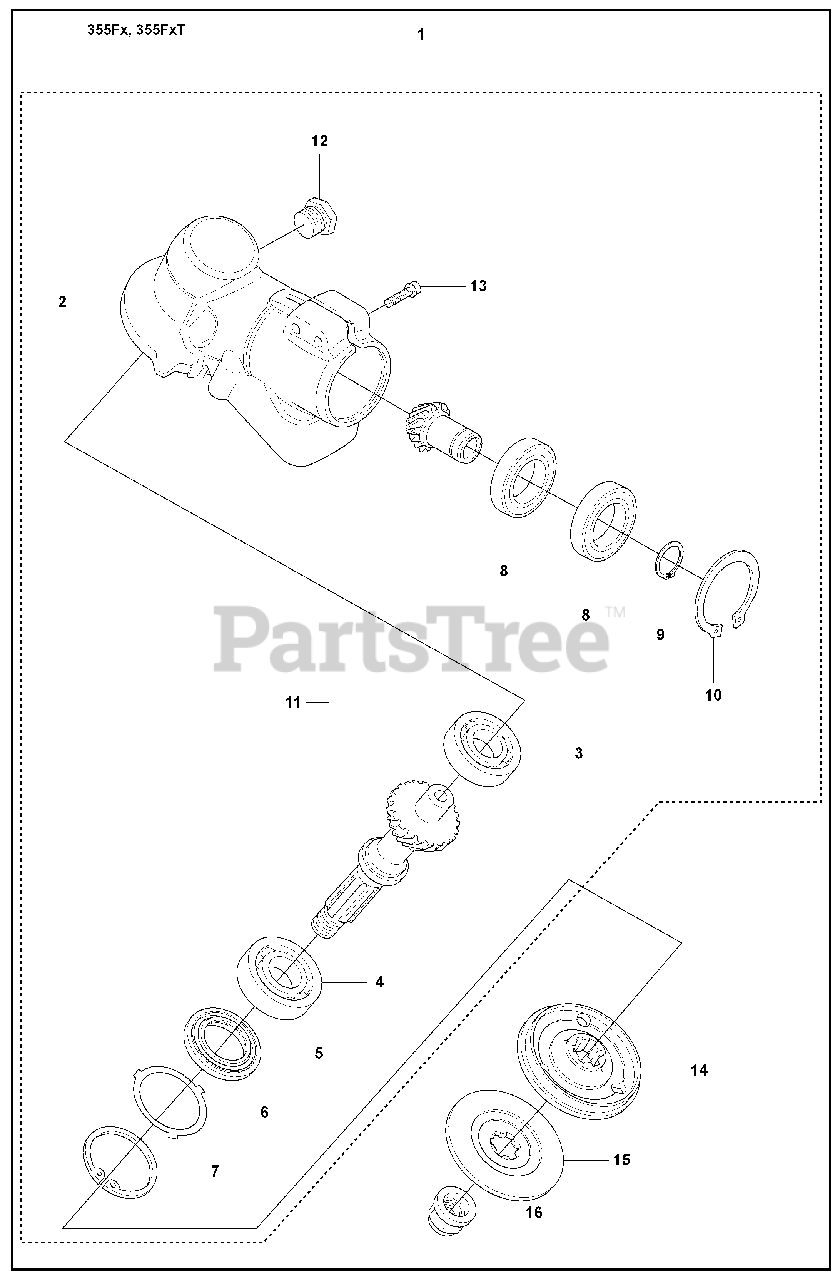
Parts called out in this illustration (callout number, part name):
2	%GEAR HOUSING
3	BALL BEARING
4	BALL BEARING
7	RETAINING RING SGH 35
8	BALL BEARING
9	RETAINING RING SGA 15
10	RETAINING RING
11	BEVEL GEAR
15	SUPPORT FLANGE
16	BLADE NUT
